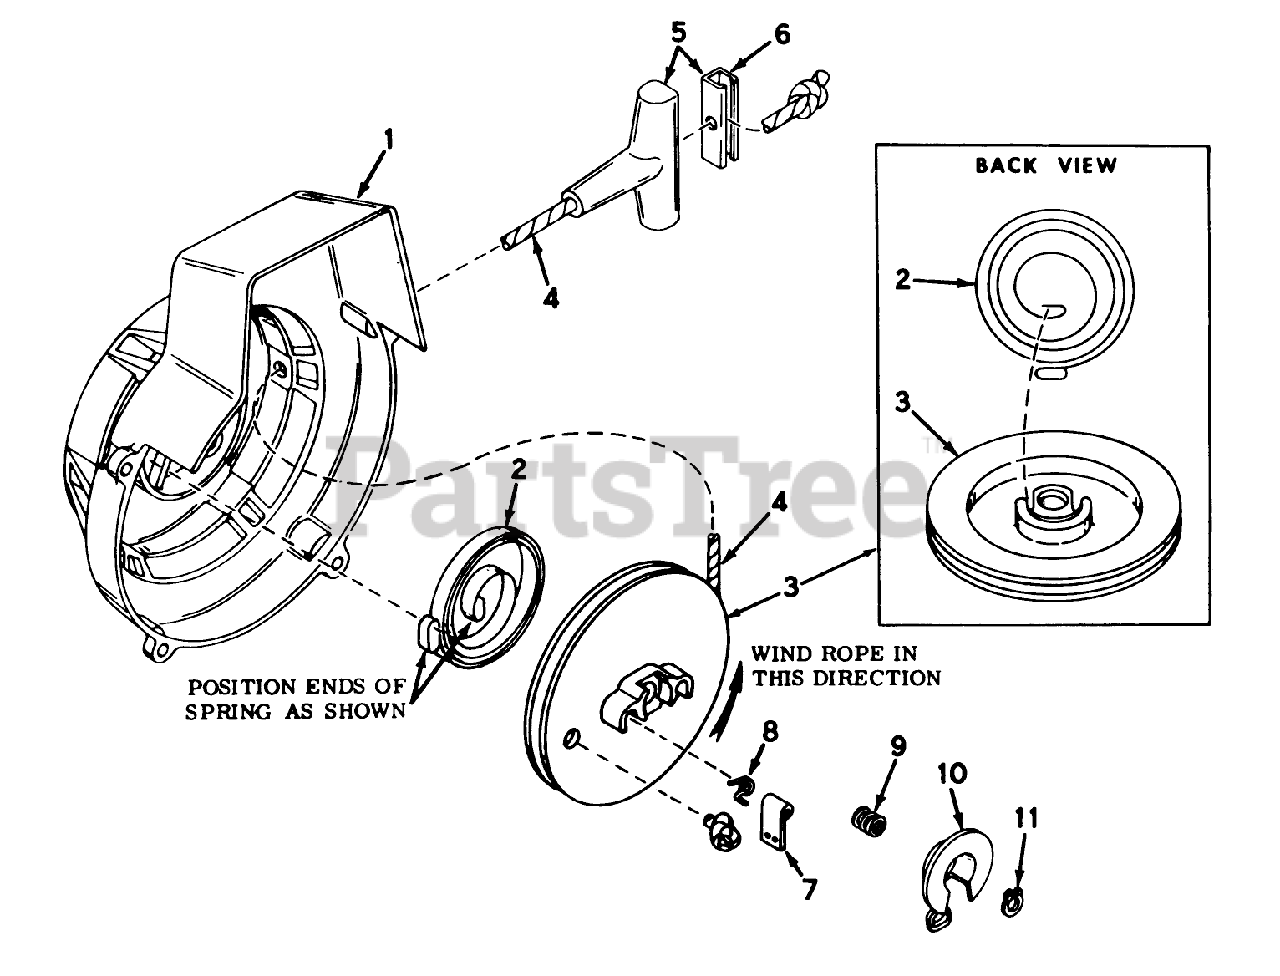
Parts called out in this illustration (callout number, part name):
1	Housing Assy., Shroud Starter
2	Spring, Rewind
3	Pulley, Starter Rope(Incl. No. 8)
4	Rope-Starter
5	Assy., Starter
6	Insert, Handle
7	Dog, Starter
8	Retum Spring, Left Hand Wound
9	Spring, Brake
10	Brake
11	E Ring Truarc
